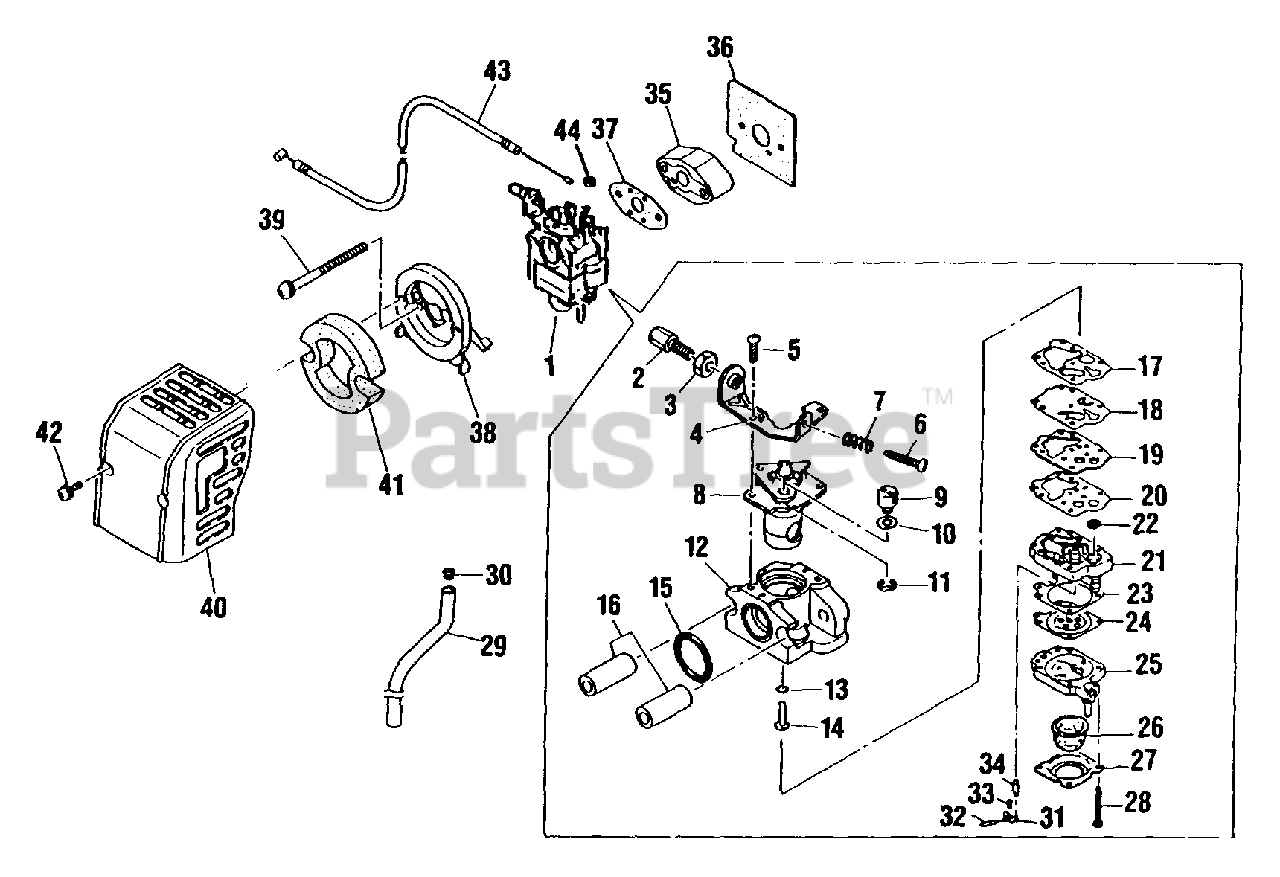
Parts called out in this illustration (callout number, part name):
1	CARBURETOR
2	NUT
2	NUT, CABLE ADJUST
3	COVER - TOP
3	NUT
4	SPRING, THROTTLE
4	BRACKET
5	PLATE, NEEDLE CLIP
5	SCREW
6	RING, RETAINING
6	SCREW, IDLE ADJUST
7	NEEDLE JET KIT
8	VALVE, THROTTLE
8	VALVE ASSY
9	SCREW, IDLE ADJUST
9	SWIVEL
10	SPRING, IDLE ADJUST
10	WASHER
11	O-RING
11	RING, RETAINING
12	NUT
12	BODY
13	CLAMP
13	O-RING
14	WASHER - 5
14	JET, MAIN
15	BOLT
16	GASKET
16	SLEEVE
17	BOLT, BANJO
17	GASKET, PUMP
18	O-RING
18	DIAPHRAGM, PUMP
18	DIAPHRAGM
19	JET
19	PLATE, PUMP
20	FLOAT
20	GASKET
21	VALVE, INLET NEEDLE
21	PUMP BODY ASSY
22	LEVER, METERING
22	SCREEN, SPARK ARRESTOR
22	STRAINER
23	PIN, METERING LEVER
23	GASKET, METERING
23	GASKET
24	SCREW - 4X6
24	DIAPHRAGM, METERING
24	DIAPHRAGM
25	SHAFT, LINK
25	BASE, PURGE
26	O-RING
26	BULB, PURGE
27	CHAMBER, FLOAT
27	RETAINER, PURGE BULB
28	SCREW - 4X12
28	SCREW
29	DRAIN TUBE
30	RING, RETAINING - 6
31	LEVER, METERING
32	PIN, METERING LEVER
32	PIN
33	SPRING, METERING LEVER
33	LEVER, SPRING
34	VALVE, INLET NEEDLE
35	INSULATOR
36	GASKET
37	GASKET, INTAKE
38	CHOKE ASSY
39	SCREW - 5X65
40	COVER, AIR FILTER
41	FILTER
42	SCREW - 4X16
43	CABLE, THROTTLE
44	RING, RETAINING
